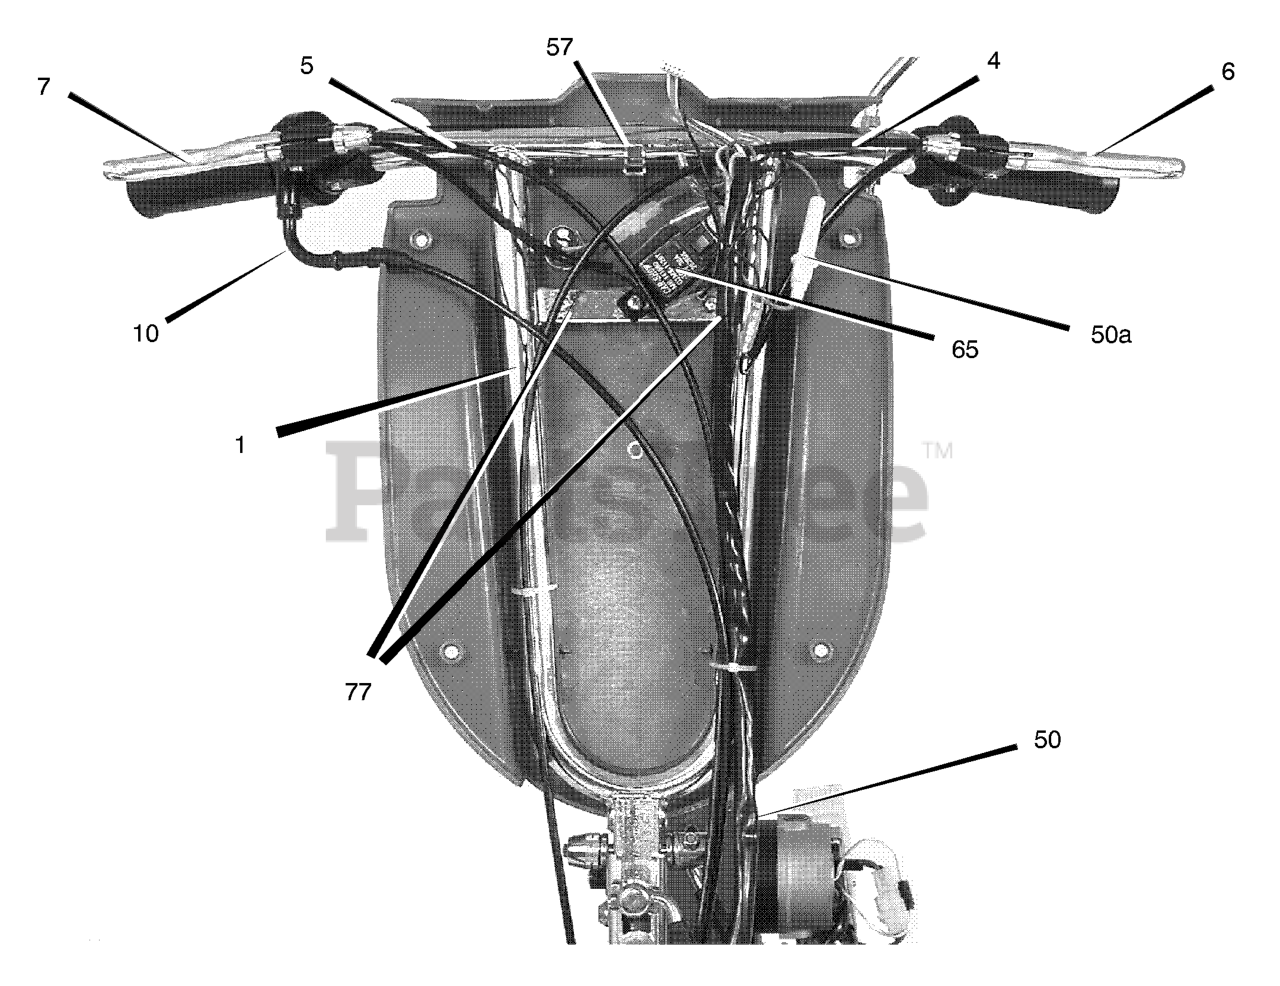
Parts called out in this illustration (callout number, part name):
1	Handlebar
4	Cable, Rear Brake-Left
5	Cable, Front Brake-Right
6	Lever, Rear Brake-w/switch
7	Lever, Front Brake-w/switch
10	Cable, Accelerator
50	Harness, Wiring-w/Fuse
50A	Fuse AGC-3 (3 amp)
57	Bracket, Headlight
65	Sensor Relay, Brake
77	Screw (2 required)
